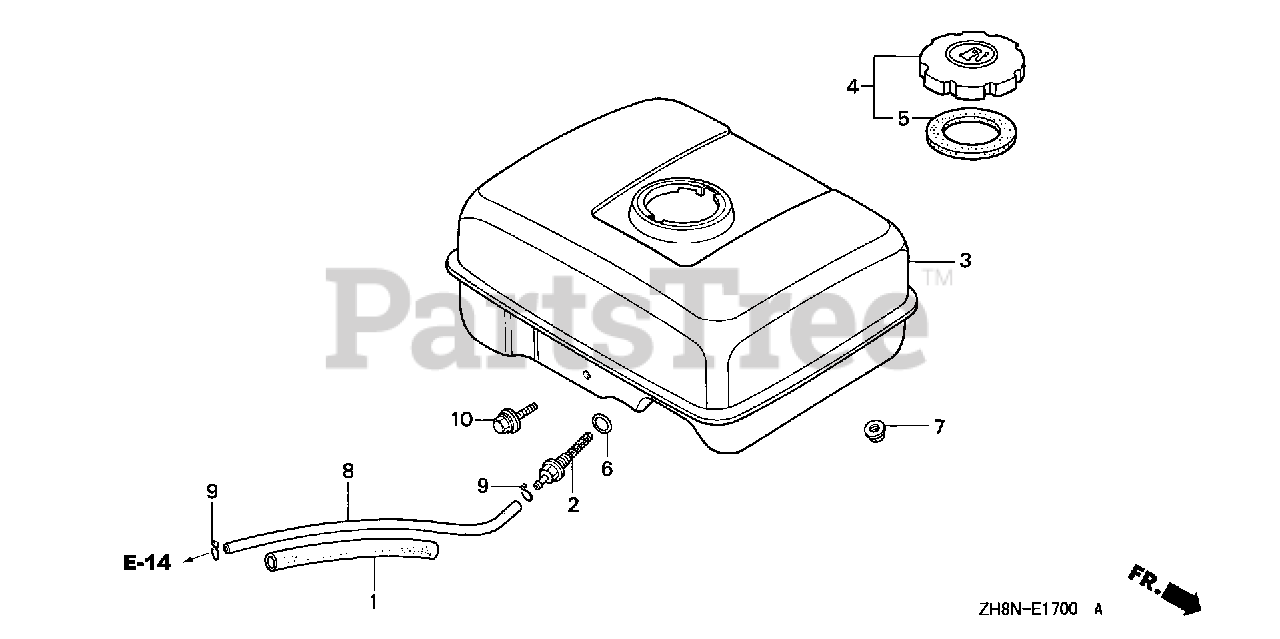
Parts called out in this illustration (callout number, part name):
1	RUBBER, SUPPORTER (107MM)
2	JOINT, FUEL TANK
3	TANK, FUEL *NH31* (MCKINLEY WHITE)
4	CAP, FUEL FILLER
5	GASKET, FUEL FILLER CAP
6	O-RING (13.5X1.5) (ARAI)
7	NUT, FLANGE (6MM)
8	BULK HOSE, FUEL (4.5X3000) (4.5X140)
9	CLIP, TUBE (B8)
10	BOLT, FLANGE (6X29)
10	BOLT, FLANGE (6X25)
